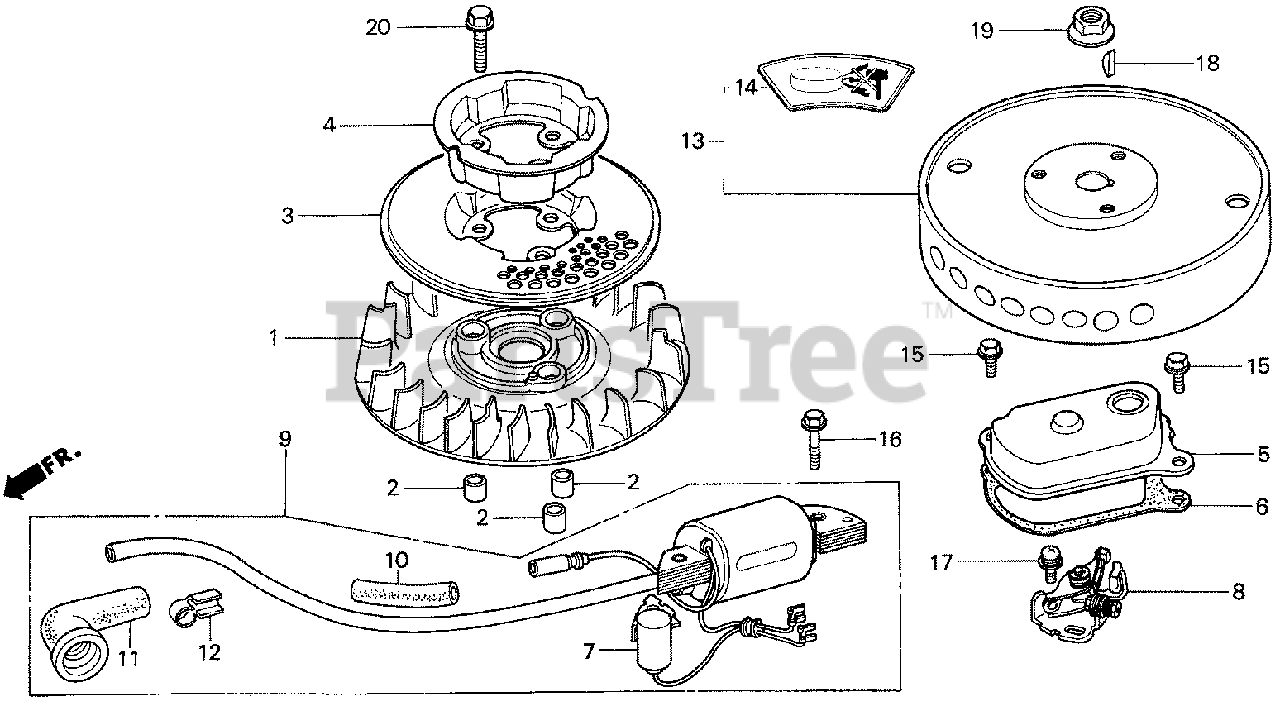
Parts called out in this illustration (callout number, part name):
1	FAN, COOLING (NOT AVAILABLE)
2	COLLAR, FAN
3	GRID, SCREEN
4	PULLEY, STARTER
5	COVER, POINTS
6	GASKET, BREAKER COVER
7	CONDENSER (NOT AVAILABLE)
8	POINTS ASSY.
9	COIL ASSY., IGNITION (NOT AVAILABLE)
10	TUBE, IGNITION RUBBER
11	CAP, IGNITION (TOYO)
12	TERMINAL, PLUG
13	FLYWHEEL
13	FLYWHEEL (NOT AVAILABLE)
14	MARK, FLYWHEEL CAUTION
15	BOLT, FLANGE (5X10)
16	BOLT, FLANGE (5X25)
17	SCREW-WASHER (5X12)
18	KEY, WOODRUFF (3MM)
19	NUT, FLANGE (12MM)
20	BOLT, FLANGE (6X22)
